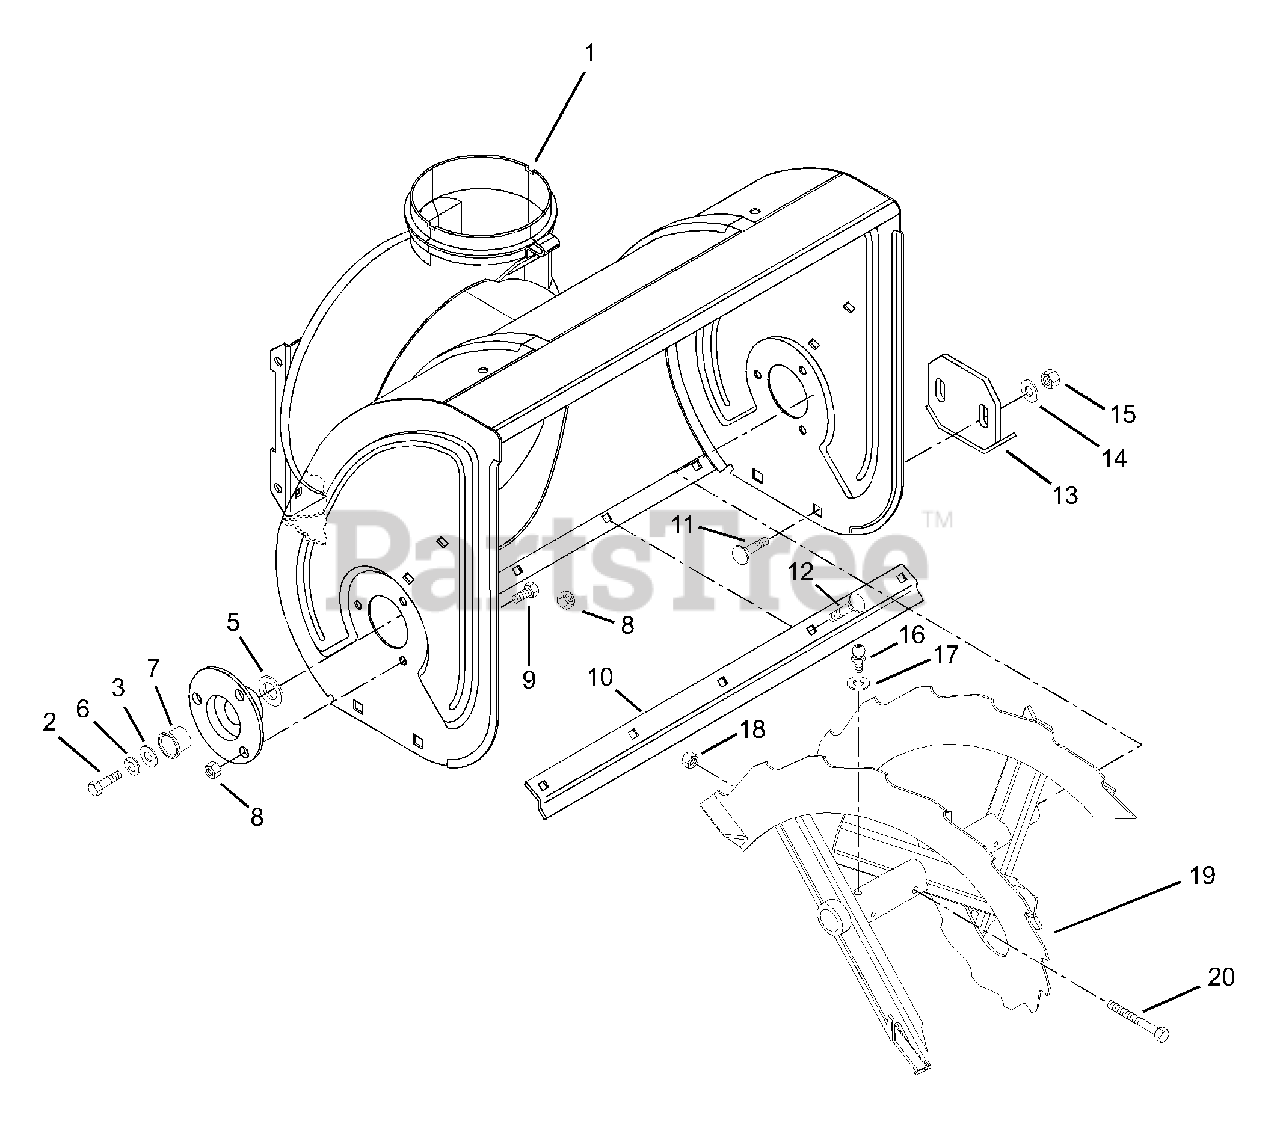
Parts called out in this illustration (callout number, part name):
1	AUGER/IMPELLER HOUSING 24"
2	@BLT-HEX .31-18X.50 GR5 YWZC
3	WSHR-FL-STL .344X1.375X.075YWZ
4	BEARING FLANGE ASSEMBLY
5	@WSHR-FL-STL.812X1.50X.135YWZC
6	@WSHR-LK .31X.078 REG YWZC
7	BSHG-FLG .750X1.000X.625X1.250
8	@NUT-SPNLK-FLG .25-20 YWZC
9	BLT-SERNK SL .25-20X.50 YWZC
10	SCRAPER BLADE
11	BLT-RHHDSQSHNK .38-16X.75 G2YZ
12	BLT-RDHDSQSHNK.25-20X.50 YWZC
13	RUNNER
14	@WSHR-FL-STL.38X.875X.083 YWZC
15	@NUT-LK-CTR .38-16 YWZC
16	FTG-LUBE .25-28X.256 YWZC
17	WSHR-FL-STL .265X.50X.087YWZC
18	@NUT-LK-CTR .25-20 YWZC
19	RAKE, RIGHT-24"(.75ID X 10.88)
19	RAKE, LEFT-24(.75ID X 10.88OD)
20	SHEAR BOLT WITH NUT
